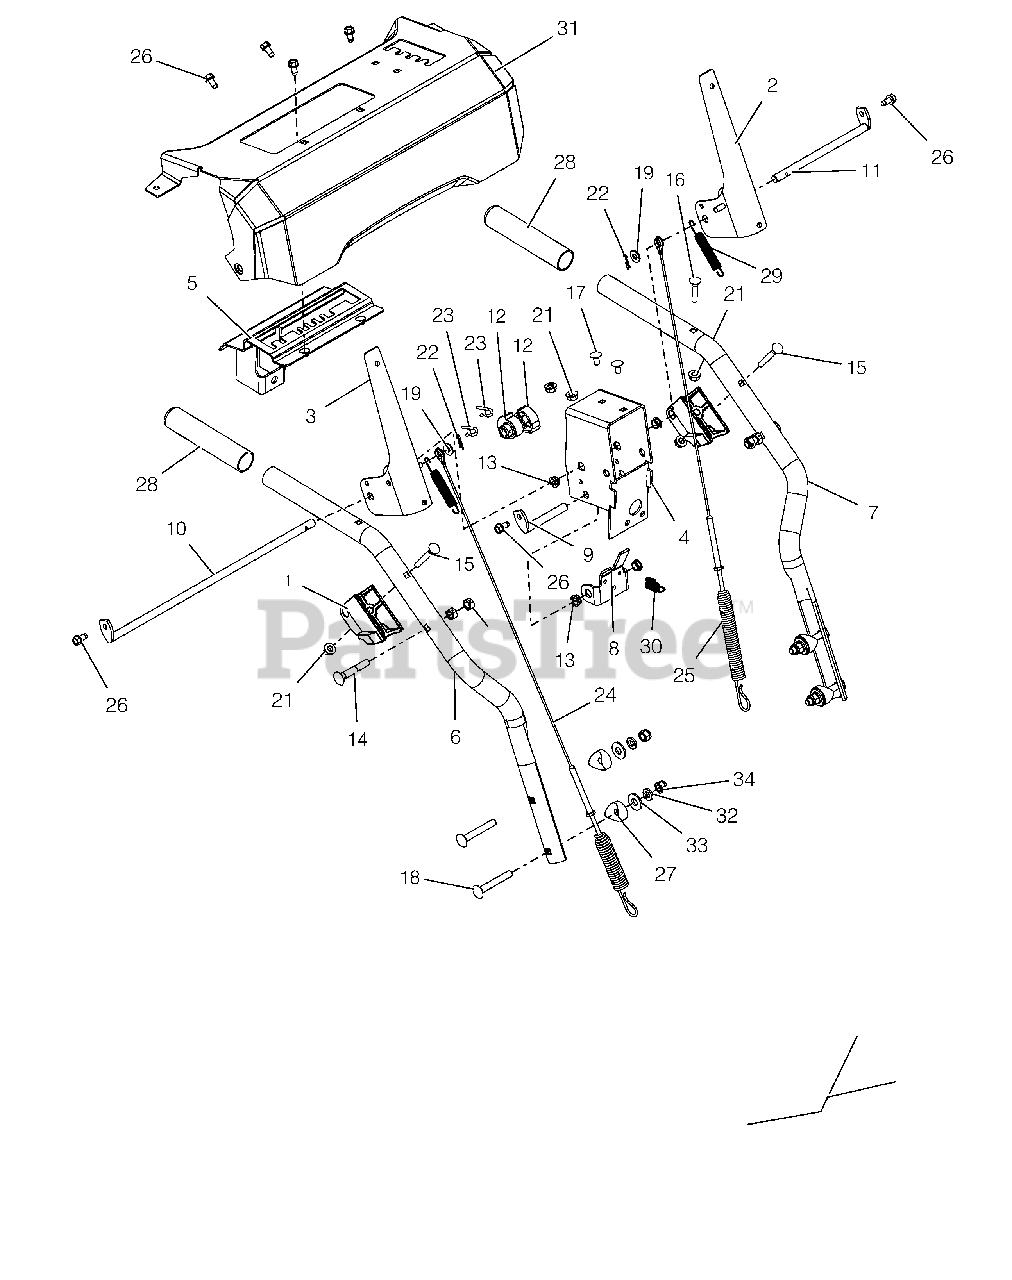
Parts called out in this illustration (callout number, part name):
1	BLOCK, CLUTCH PADDLE
2	LEVER, CLUTCH-LH
3	LEVER, CLUTCH-RH
4	WELDMENT, BRACKET INTERLOCK
5	WELDMENT, DETENT PLATE-COMPACT
6	HANDLEBAR, UPPER - RH
7	HANDLEBAR, UPPER - LH
8	BRACKET, INTERLOCK ARM
9	ROD, INTERLOCK PIVOT
10	ROD, PADDLE MOUNT - LONG
11	ROD, PADDLE MOUNT - SHORT
12	CAM, INTERLOCK
13	BUSHING, POLYLINER-.38 SNAPIN
14	BLT-RDHDXLSQNK .31-18X2.0 G5YZ
15	BLT-RDHDXLSQNK .25-20X2.0 G5YZ
16	BLT-RDHDXLSQNK.25-20X1.25 G5ZC
17	@BLT-RDHDSQNK .25-20X.50 G5YZ
18	@BLT-RDHDSQNK .31-18X2.25 G5YZ
19	@WSHR-FL-STL.281X.62X.065 YWZC
20	@NUT-LK-CTR .31-18 YWZC
21	@NUT-LK-TOP-FLG .25-20 YWZC
22	PIN-HAIR INT .06X.18X.77
23	PIN, SPRING CLIP
24	CABLE, AUGER (DELUXE & PRO)
25	CABLE, UPPER TRACTION
26	SCR-TAP .25-20X.50 HWH TR YWZ
27	SPACER, HANDLEBAR
28	GRIP,HANDLE-GRAY
29	SPRING, EXTENSION
30	SPRING-EXT .047X.438X1.45
31	CONTROL PANEL W/DECAL, BRUSH
32	WSHR-LK .312X.097 HVY YWZC
33	@WSHR-FL-STL.38X.875X.083 YWZC
34	@NUT-LK-NYL .312-18 YWZC
